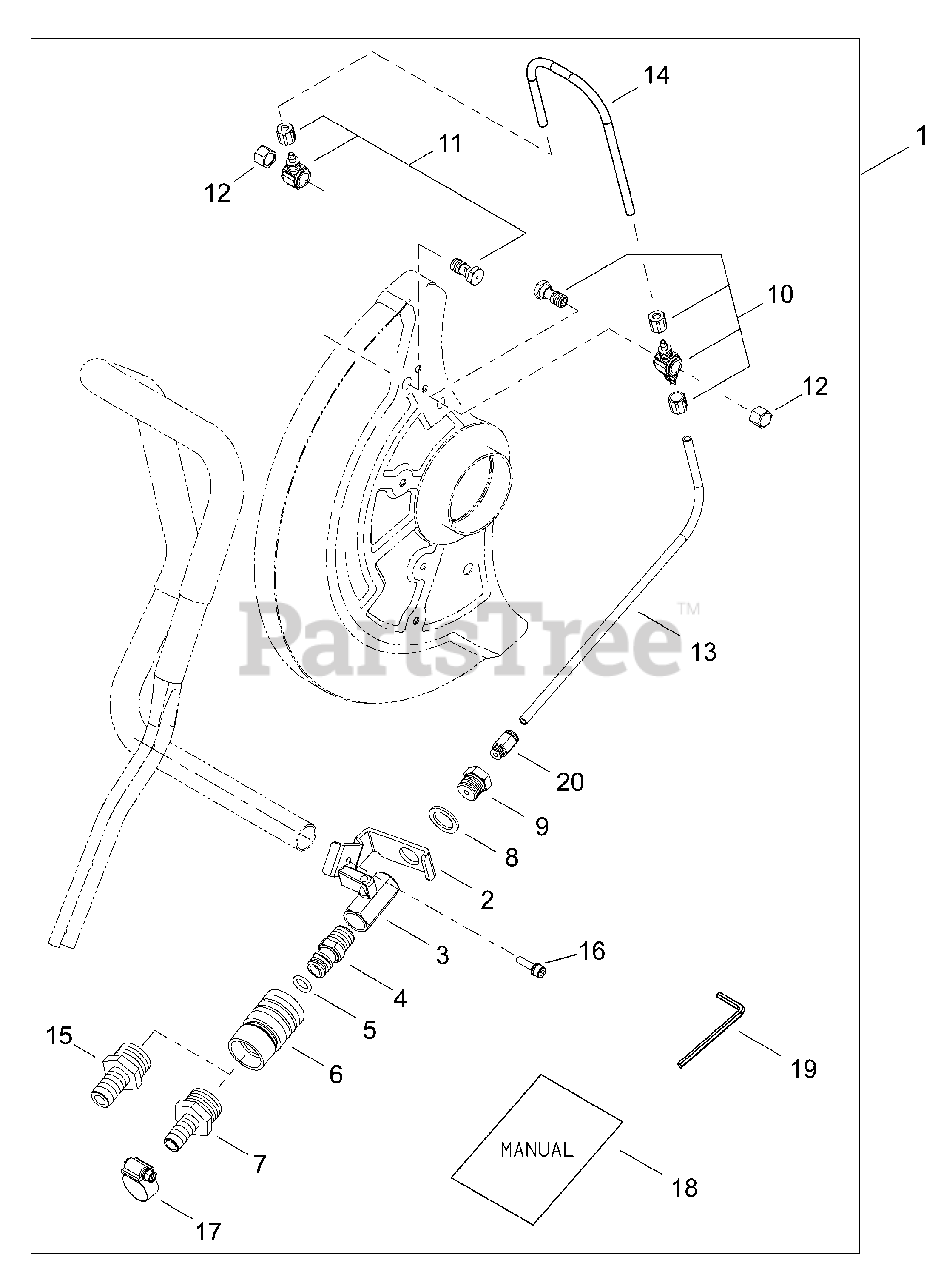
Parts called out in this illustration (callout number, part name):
1	WATER KIT
2	BRACKET
3	VALVE
4	FITTING, QUICK DISCONNECT - MALE
5	O-RING
6	FITTING, QUICK DISCONNECT - FEMALE
7	1/2" HOSE FITTING OUTSIDE DIAMETER14
9	FITTING - MALE
10	DOUBLE NOZZLE MOUNT ASSY
11	SINGLE NOZZLE MOUNT ASSY
12	CAP - BRASS
13	TUBE - 370
14	TUBE - 235
15	5/8" HOSE FITTING OUTSIDE DIAMETER17
16	SCREW - 5X20
17	CLAMP, HOSE
18	OWNER'S MANUAL
19	HEX KEY - 4mm
20	CONNECTOR
